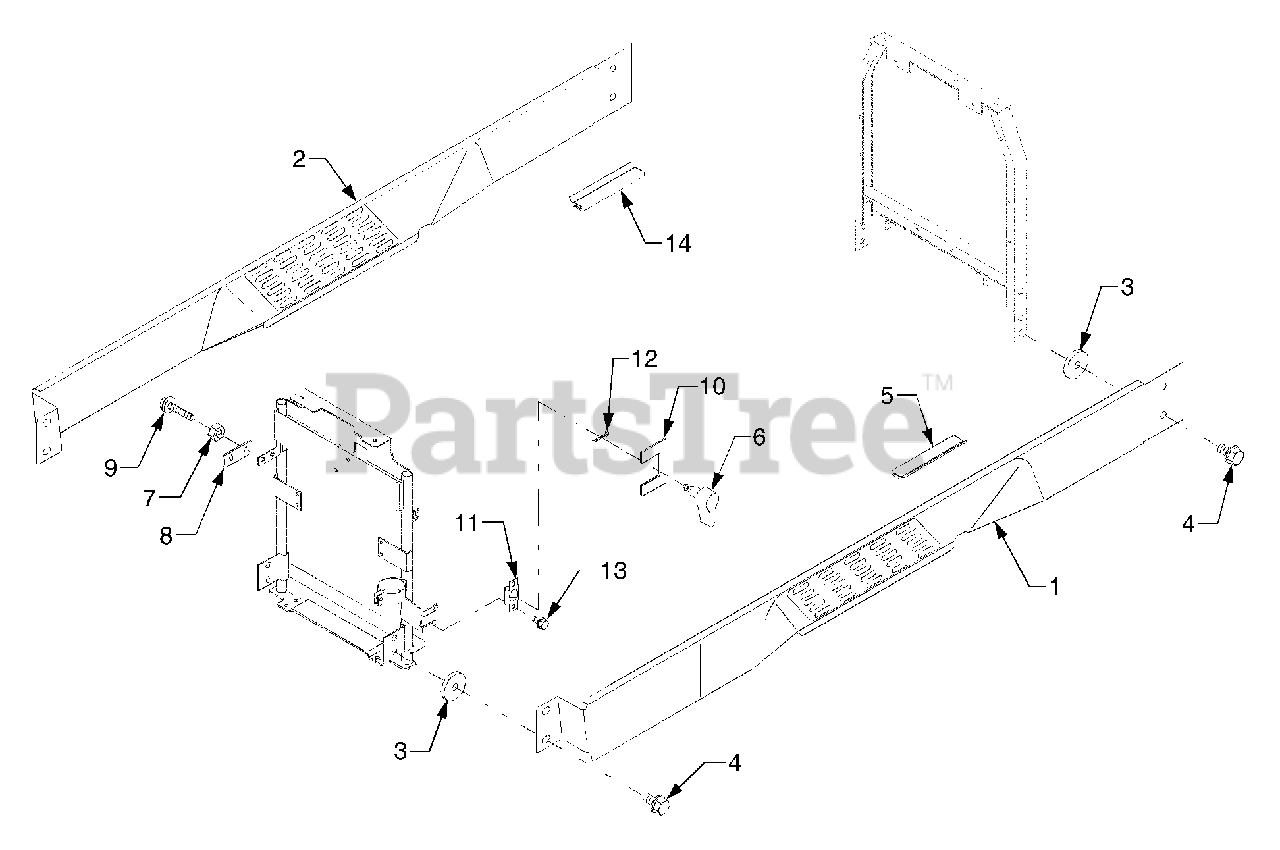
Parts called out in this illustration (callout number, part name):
1	Cover, Low (LH)
2	Cover, Low (RH)
5	Rubber, Cover (LH)
6	Knob, Side Cover
8	Plate, Side Cover
9	Bolt, Cushion
10	Rubber (Bonnet-LH)
14	Rubber, Cover (RH)
